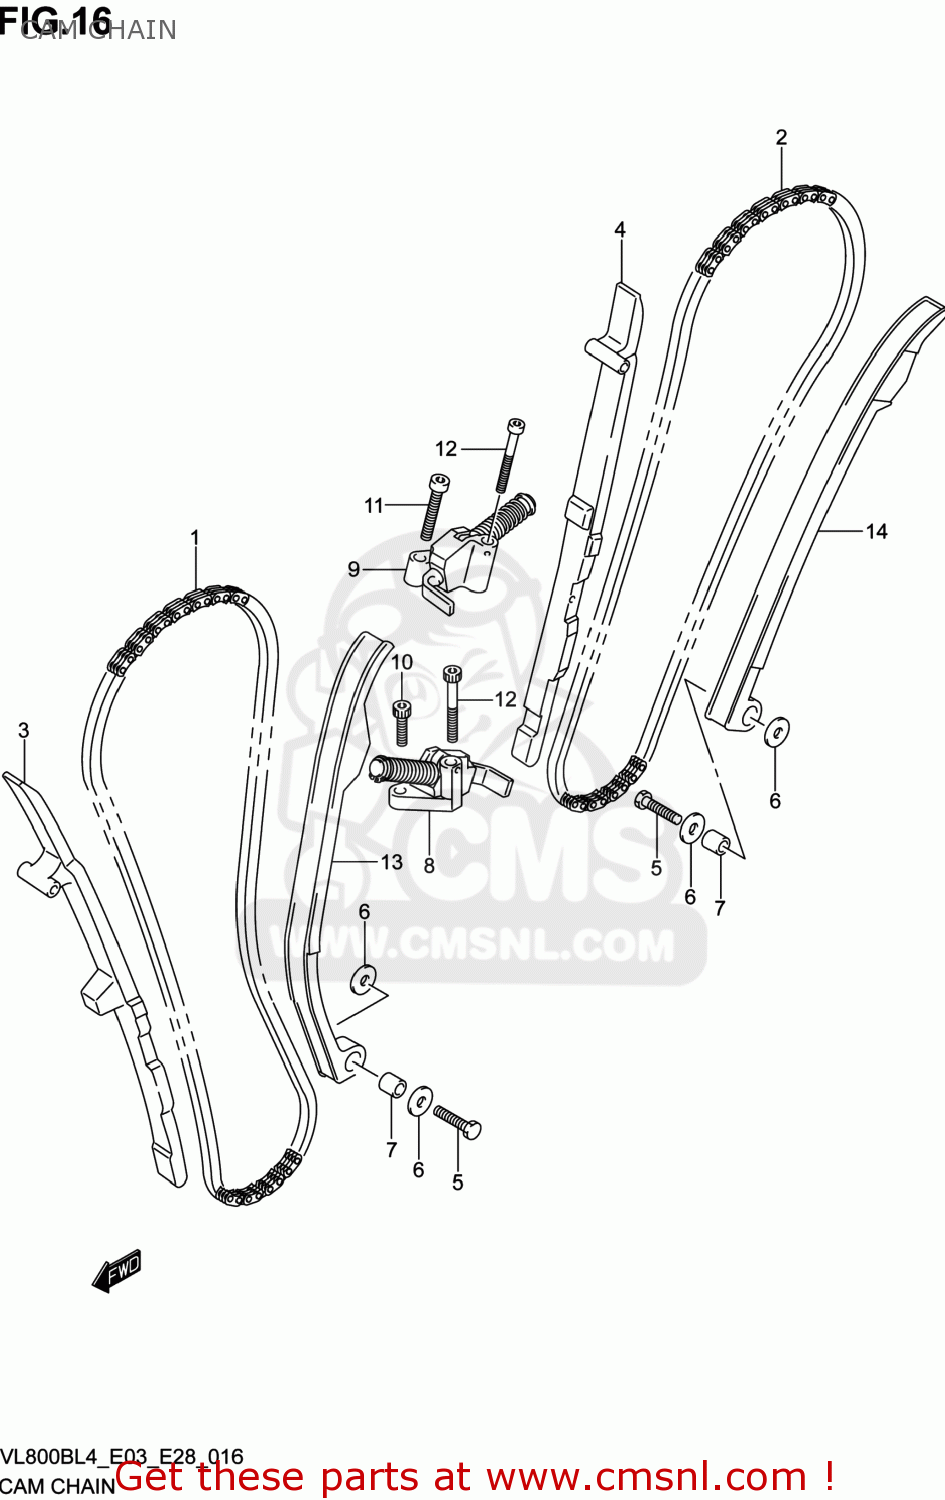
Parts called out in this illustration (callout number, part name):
1	CHAIN,CAMSHAFT DRIVE FR
2	CHAIN,CAMSHAFT DRIVE RR
3	GUIDE,CAM CHAIN
4	GUIDE,CAM CHAIN RR
5	BOLT(6X26)
6	WASHER
7	SPACER(6X11X11)
8	ADJUSTER ASSY,FR TENSIONER
9	ADJUSTER ASSY,TENSIONER RR
10	BOLT
11	BOLT
12	BOLT
13	TENSIONER,CAM CHAIN
14	TENSIONER,RR CAM CHAIN
